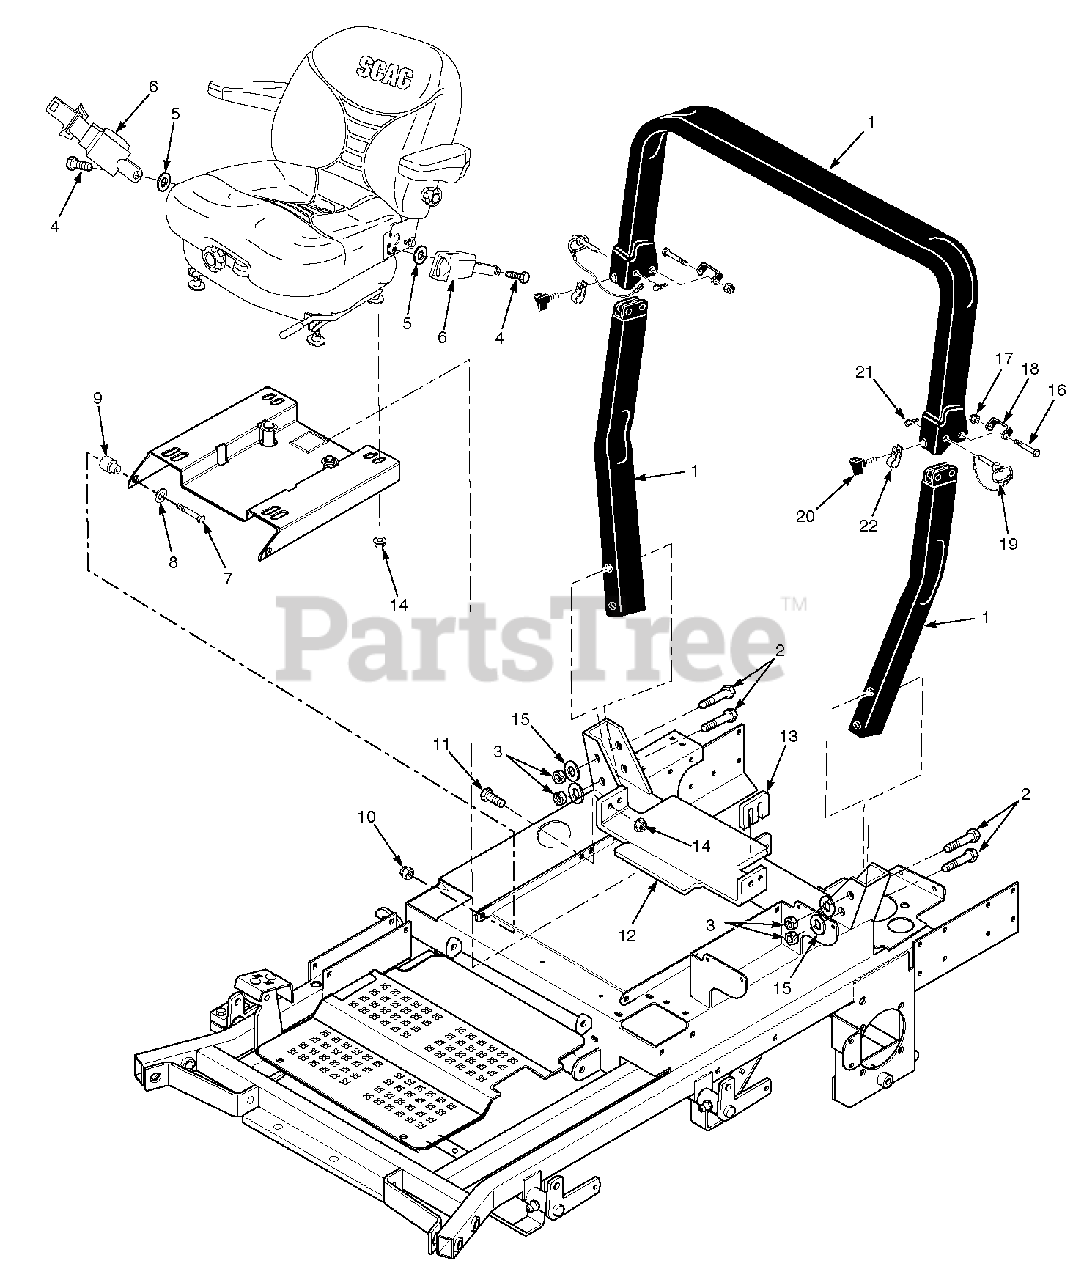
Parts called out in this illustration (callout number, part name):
1	STT, ROPS Accessory (Incl. all items below)
2	Bolt, Hex Hd. 1/2-13 x 4-1/2"
3	Nut, Center Lock 1/2-13
4	Bolt, Hex Hd. 7/16-20 x 1"
5	Flatwasher, 7/16 (.500 x 1.25 x .083")
6	Retractable Seat Belt
7	Bolt, Hex Hd. 3/8-16 x 2"
8	Flatwasher, 3/8 (.391 x .938 x .105")
9	Sleeve, Seat Base Mounting
10	Nut, Elastic Stop 3/8-16
11	Bolt, Hex Hd. 5/16-18 x 1"
12	Bracket, Seat Hold Down w/Decal
13	Spacer, Seat Hold Down
14	Nut, Serr. Flng. 5/16-18
15	Flatwasher, 1/2 (.562 x 1.375 x .109")
16	Bolt, Hex Hd. 1/2-13 x 3-1/2"
17	Nut, Center Lock 1/2-13
18	Bracket, Stop
19	Pin
20	Thumb Screw, 5/16-18 NC x 3/4"
21	Hair Pin, Cotter
22	Clamp
